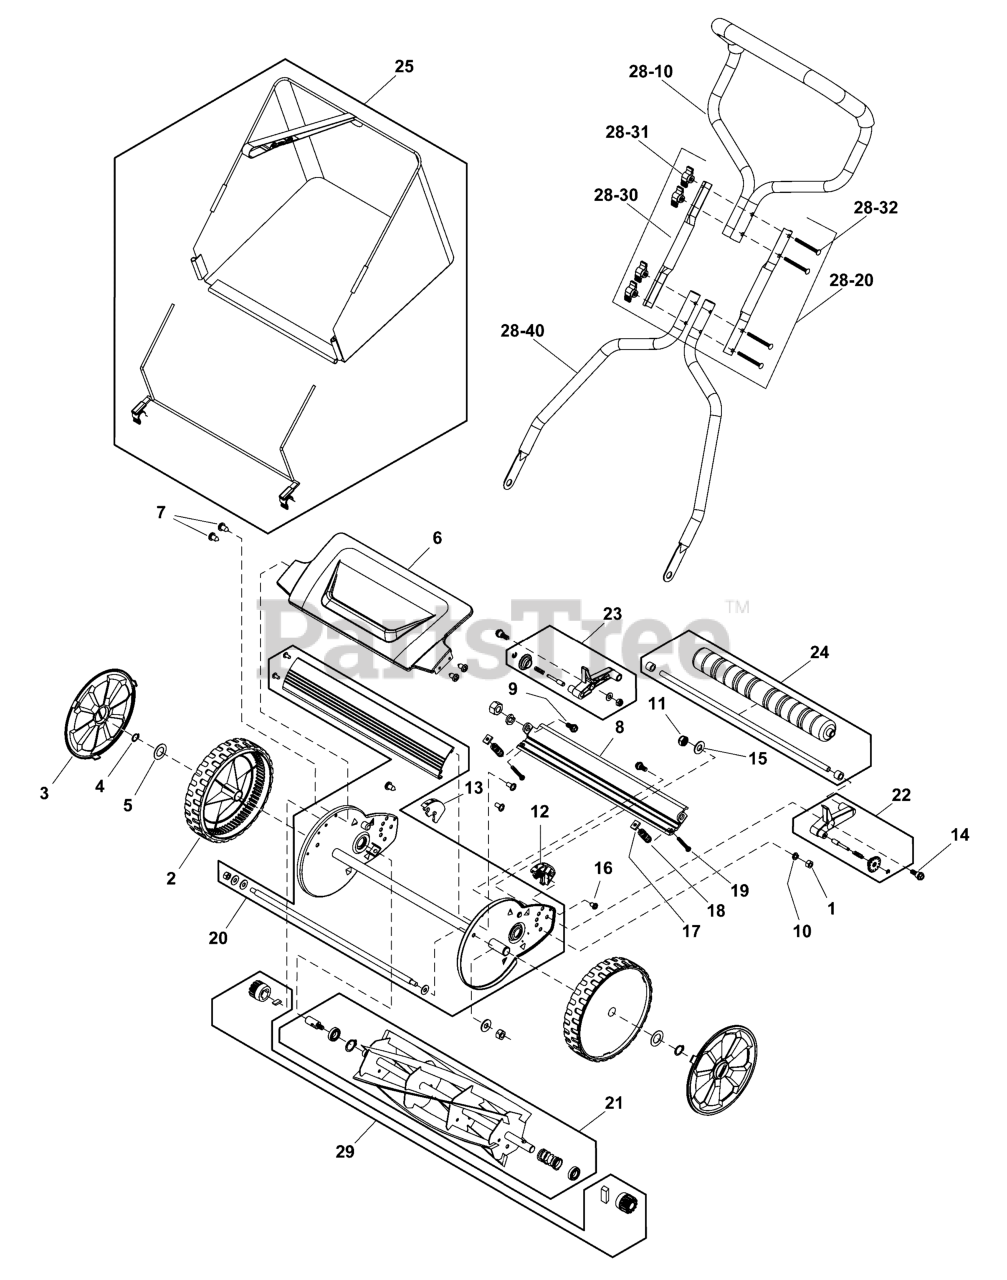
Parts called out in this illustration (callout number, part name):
1	NUT M8, Nylock
8	BLADE, Fixed
10	WASHER, Spring
12	INDICATOR, Cutting Height, Left
13	INDICATOR, Cutting Height, Right
18	SPRING
20	CHASSIS
21	BLADE, Reel
22	BRACKET, Rear Roller, Left
23	BRACKET, Rear Roller, Right
24	ROLLER, Rear
25	GRASS CATCHER ASSEMBLY, Fabric, Murray
28-10	HANDLE, Top
28-20	KIT, Knobs & Fasteners, Green
28-30	HANDLE, Middle
28-31	KNOB
28-40	HANDLE, Lower
29	GEAR KIT
